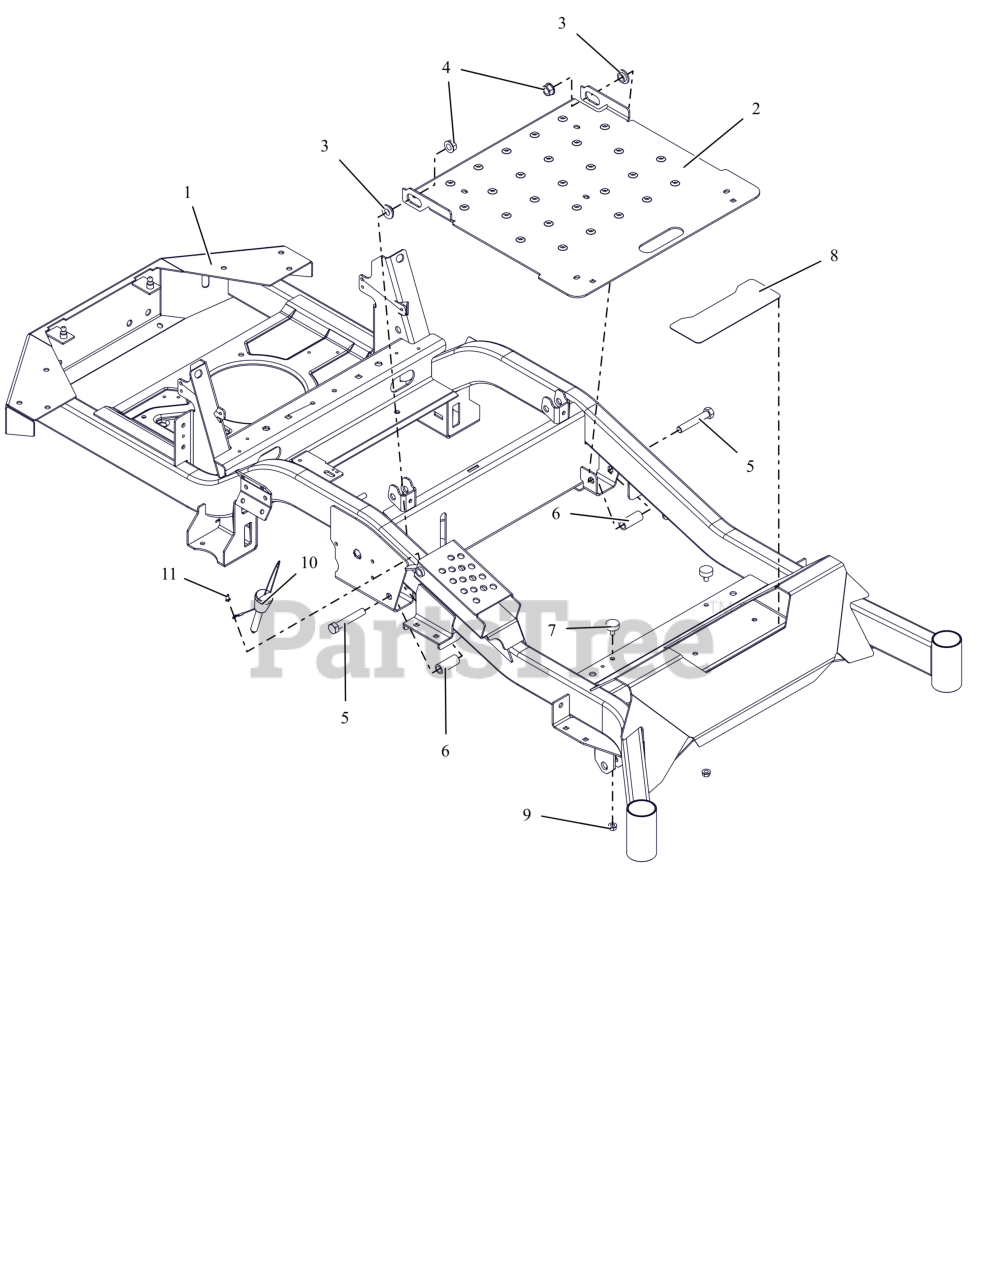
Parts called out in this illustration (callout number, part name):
1	WLDMT, MAIN FRAME -APEX 44-52 (ORANGE)
2	PANEL, ACCESS
3	BSHG-FLG .515X.750X.395X1.120
4	NUT-LK-TOP-FLG .500-13 GF ZCC
5	BLT, HEX .50-13X3.00 G5 ZCC
6	SPACER, .515X.75X1.83
7	BUMPER, RUBBER
8	GRIP, STEP
9	NUT,SPNLK-FLG .31-18 G5 ZCC
10	PIN- MAGNETIC .50X2.70
11	POST, & SCREW, PUSH LOCK .25 X .25
